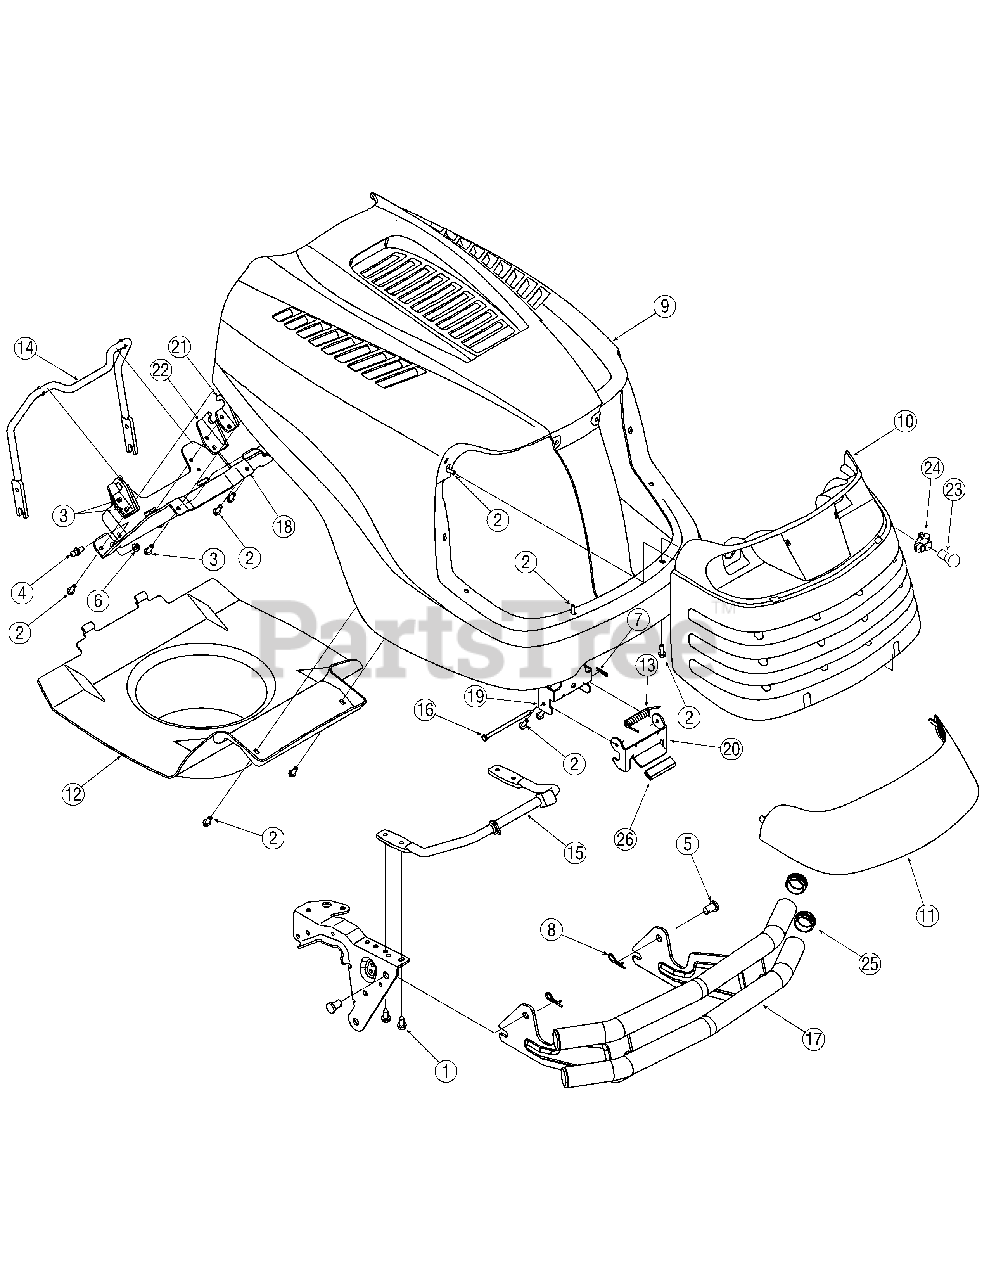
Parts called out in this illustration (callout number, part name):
1	Screw, 5/16-12 x.750
2	Screw, 1/4-15 x.750
3	Screw, Self Tapp, 1/4-20 x.750
4	Screw, Ball, 5/16-18 x.56
5	Pin, Clevis,.50 Dia. x.78
6	Nut, Flange Lock, 5/16-18
7	Pin, Cotter,.072 Dia. x 1.13
8	Pin, Click,.092 x 1.64
9	Hood, Service Kit
9	Hood
9	Push Nut .25ID x .50 OD
9	Screw, Hi Low 5/16-14 x .75
10	Grill
11	Lens
12	Hood Plenum
13	Latch Spring
14	Hood Pivot Rod
15	Hood Latch Rod
16	Rod,.250 Dia. x 4.55
20	Latch Pivot Bracket
21	Upper Pivot Bracket
22	Hood Pivot Bracket
23	Miniature Lamp, 12V
24	Lamp Socket
25	Cap, Bumper
26	Vinyl Strip, 2.5"
